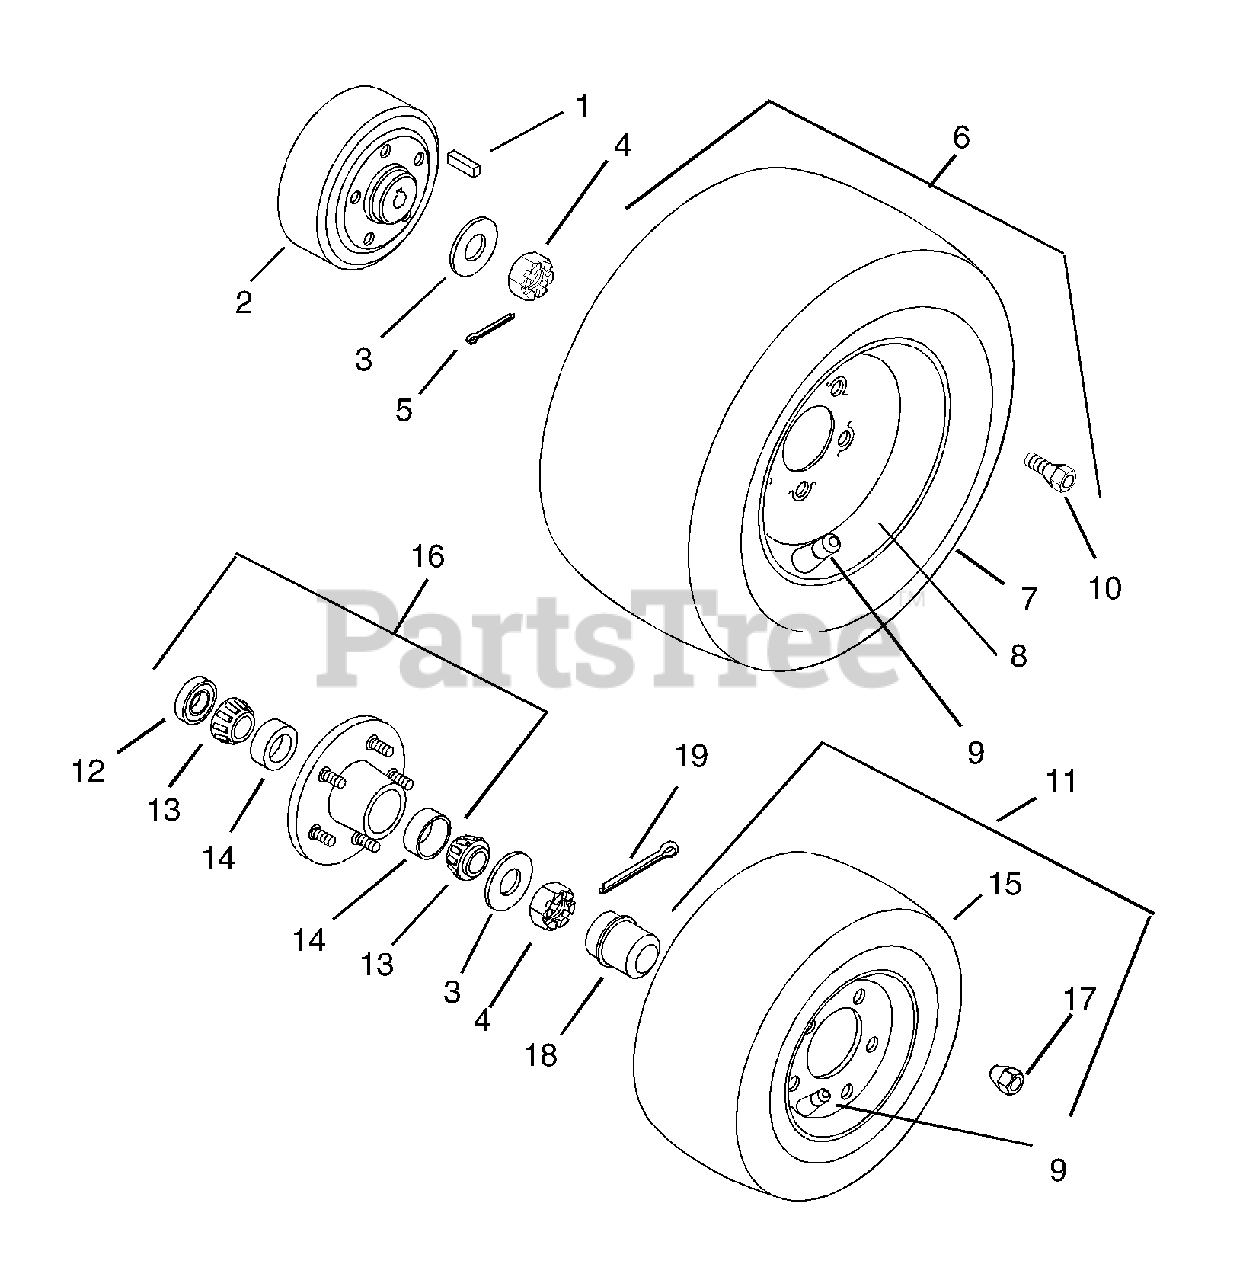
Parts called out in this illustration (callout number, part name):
1	Key-Feather .25 X 1.875 X .25
2	Hub
3	Washer-Flat-Steel .812 X 1.50 X .139
4	Nut-Slotted .75-16
5	Pin-Cotter .18 x 1.50
6	Tire/Wheel Assembly 23 x 10.50-12
7	Tire 23 x 10.50-12
8	Weldment, Rim
9	Valve Stem Assembly
10	Bolt-Lug .50-20 x .75 x 1.62
11	Assembly-Tire and Wheel
12	Seal 1.206 x 1.785 x .468
13	Bearing-Cone 1.0 x .58
14	Bearing-Cup 1.78 x .420
15	Tire 16 x 7.50-8
16	Assembly, Hub
17	Nut-Lug .50-20
18	Dust Cap
19	Pin-Cotter .12 x 1.25
20	Assembly-Tire-Wheel and Hub
